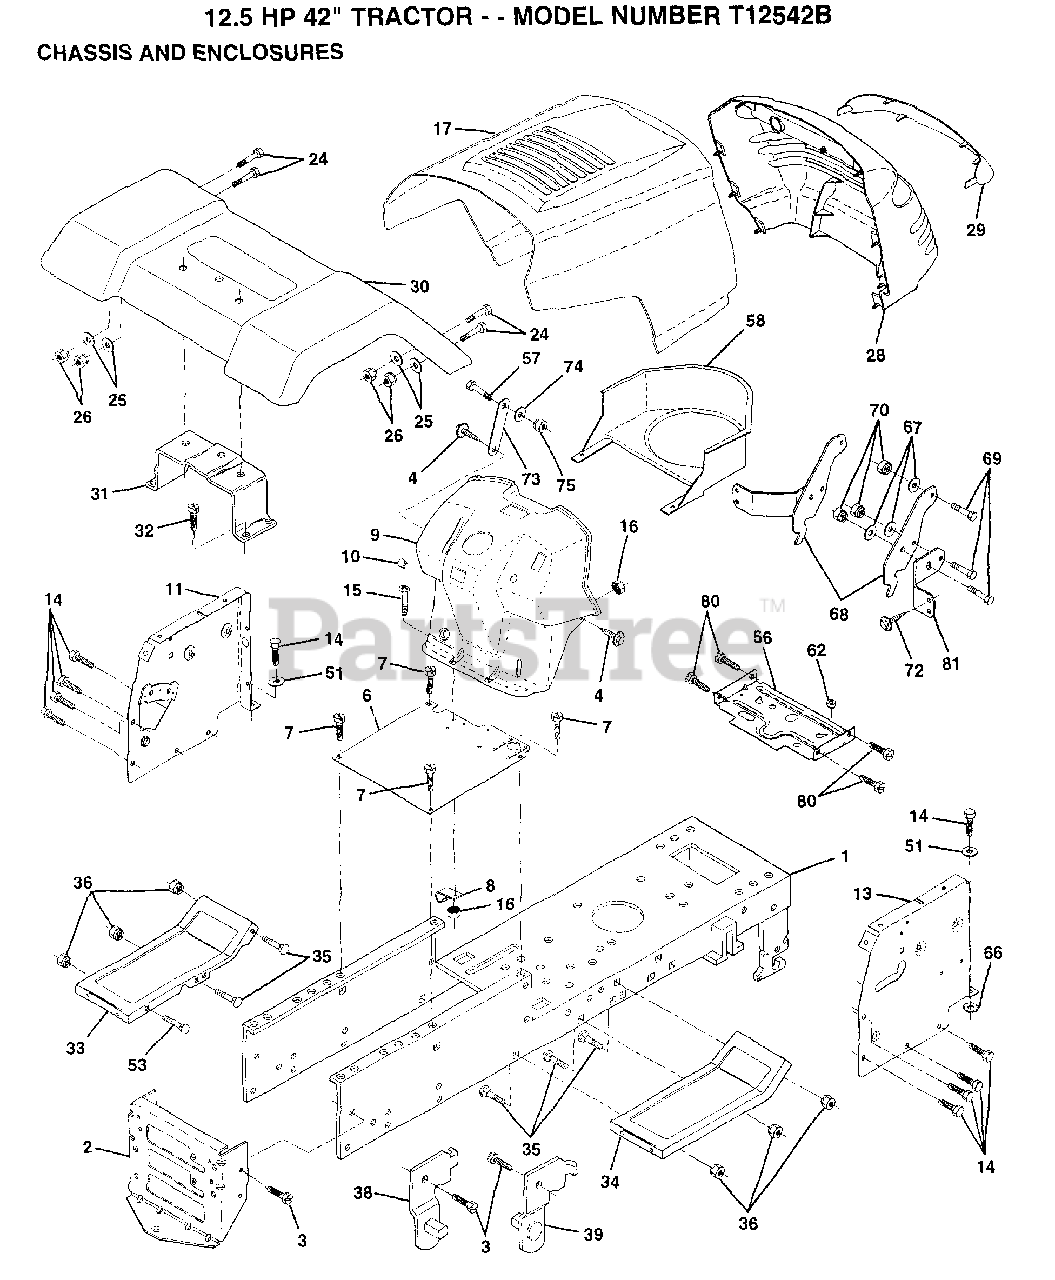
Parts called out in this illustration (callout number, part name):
3	SCREW
4	SCREW HEX CRT
7	SCREW
8	CLIP T
10	PLUG BUTTON T
14	SCREW LT
16	NUT
17	HOOD.PNT.STEEL
24	BOLT
25	WASHER
26	NUT
29	LENS GRILLE
31	BRKT FENDER
32	SCREW
33	FOOTREST LH
34	FOOTREST
35	BOLT
36	NUT
38	BRACKET ASM LH
39	BRACKET ASM RH
51	WASHER
58	DUCT AIR 12-15H
66	LOCKWASHER
67	WASHER
68	HING PICK-OFF HD
69	BOLT LT
73	BRACE SUPT DASH
74	WASHER
75	NUT
80	SCREW
81	BRACKET GRILLE
